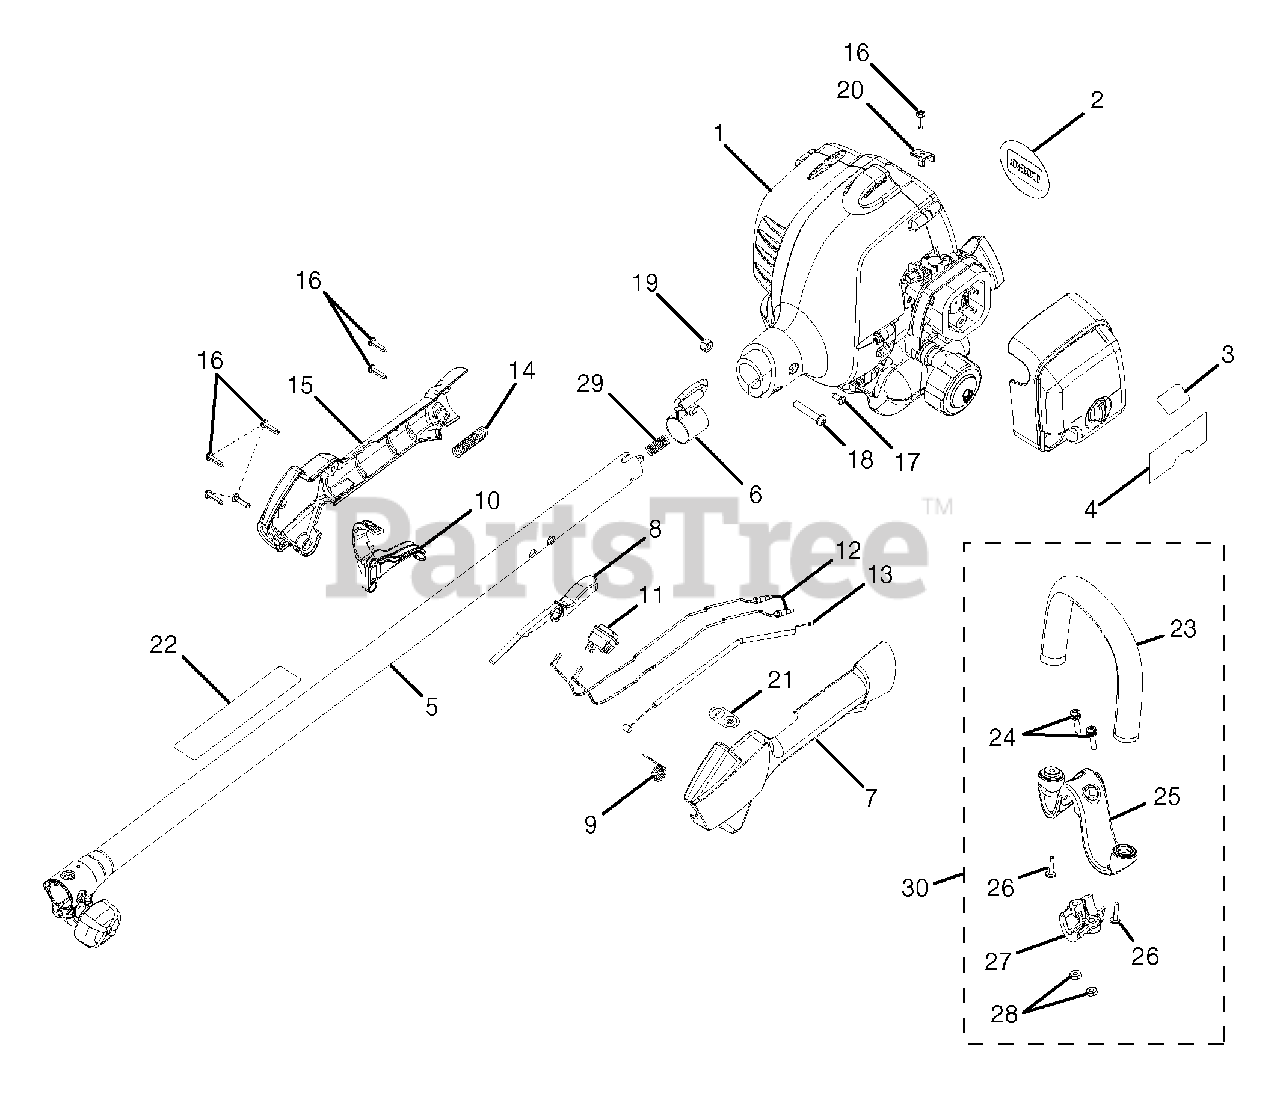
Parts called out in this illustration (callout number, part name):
1	Engine Assembly
2	Logo Label
3	Upper Start Label
4	Lower Start Label
5	Upper Shaft Assembly
6	Hanger Bracket
7	Rear Handle Support
8	Lock-off Button
9	Trigger Spring
11	Switch with Dust Shield
13	Cable, Throttle
14	Corrugated Tube
15	Rear Handle Cover
16	Screw, (M4 x 1.75 x 16mm)
17	Screw, (#8-16 x 1/2 in., Tri-lobular)
18	Screw, (M6 x 1 x 30mm)
19	Hex Nut
20	Retaining Clip
21	On/Off Label
22	Warning Label
23	Assist Handle w/grip
24	12-24 x 1SEMS
25	M Clamp
26	Slotted Torx Screw
28	12 - 24 Hexnut
29	Spring, Shaft
30	Assist Handle Assembly
